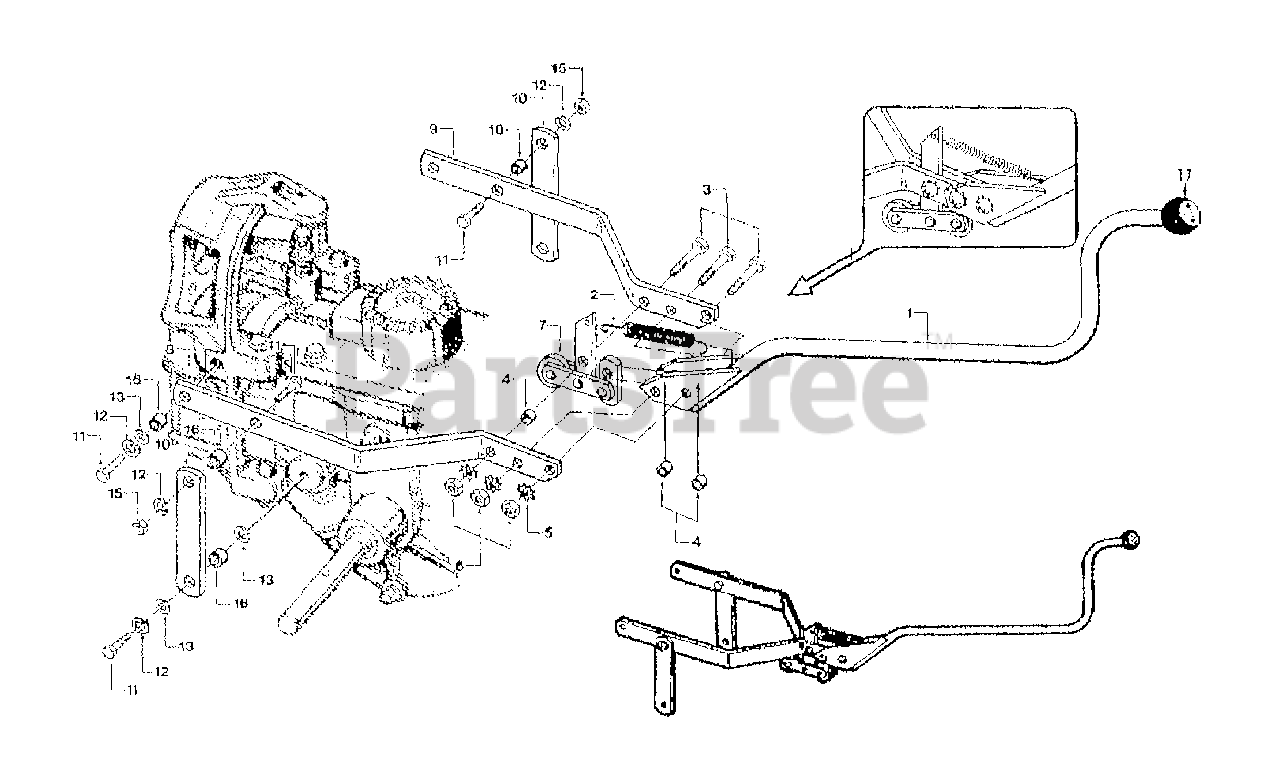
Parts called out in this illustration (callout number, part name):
1	ASSM-FOR/REV LEVER (INCL. KNOB W/DECAL)
2	SPRING-.436 X 3.25
3	SCR-HH 5/16-18X1.5 G5 ZP
4	BUSHING-.5X.316X.375 PM
5	WASHER-LK .312 EXT TOOTH
6	NUT-HEX 5/16-18 ZP
7	ASSM-ROLLER PAINT
8	YOKE-LH RED
9	YOKE-RH RED
10	YOKE-RED 2164
11	SCR-HH 3/8-16X1.0 G5 ZP
12	WASHER-LK .375 @ DEPL
13	WASHER-FLAT 3/8 SAE
14	THIS REF. NO. NOT USED
15	NUT-HEX 3/8-16 ZP
16	BUSHING-.5X.375X.3 (.300")
17	KNOB - NOT AVAIL. SEPARATELY. SEE REF. NO. 1
